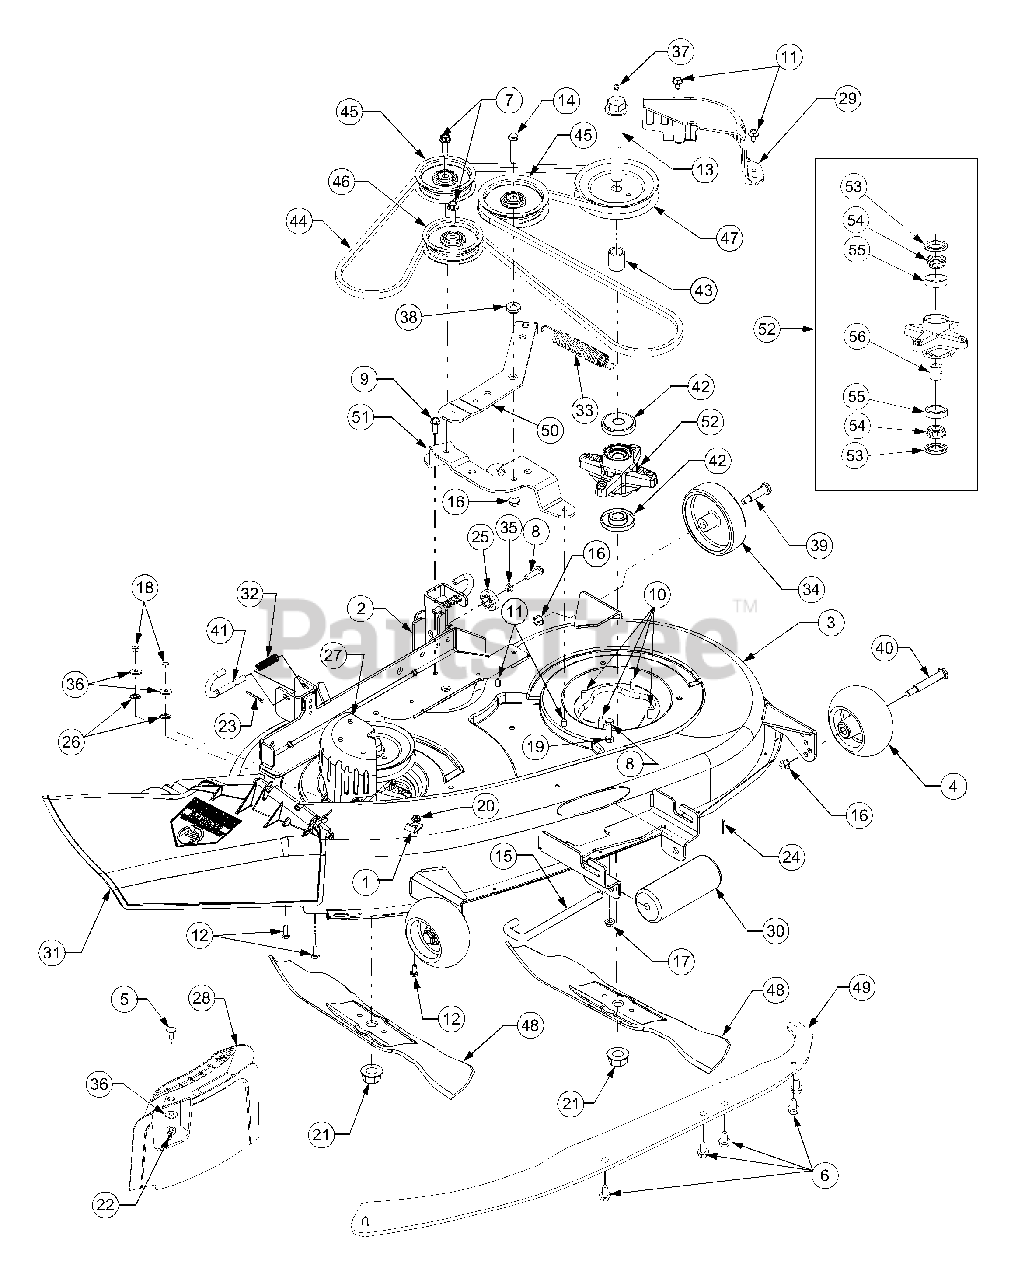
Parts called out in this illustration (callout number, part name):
1	Bracket, Hook, Retainer
5	Screw, Carriage, 1/4-20 x .62
6	Screw, Hx. Wash, Hd,Tapp 1/4-20 x .5
7	Screw, Hx. Wash, Hd, Sems Tapp 3/8-16 x 1.25
8	Screw, 5/16-18, 1.25, Gr5
9	Screw, Hx. Wash, Hd, Tapp, 5/16-18 x 1.0
10	Screw, Hx. Wash, Hd, Tapp, 5/16-18, 0.875
11	Screw, Hx. Wash, Hd, Tapp, 5/61-12 x .75
12	Screw, 1/4-20, .620, Gr5
13	Bolt, Spindle, 3/4-16, 5.85 (solid bolt, no grease fitting)
13	Bolt, Spindle, 3/4-16, 5.85 Greaseable spindle (No longer available) replace with 710-04226, 618-04217 & 737-3000
14	Screw, Hx. Cap, 3/8-16, 2.00, Gr5
15	Roller Pin 1/2" x 7.31 Lg
16	Nut, Hx. Flange Lock, 3/8-16
17	Nut, Hx. Flange Lock, 5/16-18, Gr5
18	Nut, Hex, 1/4-20, Gr5
19	Nut, Hex, 5/16-18, Gr5
20	Nut, Hx. Flange Lock, 1/4-20
21	Nut, Hx. Flange, 3/4-16
22	Nut, Wing, 1/4-20
23	Pin, Cotter, 1/8 x 1.25
24	Pin, Cotter, 3/32 x 1.25
25	Adjustment Gear, Deck
26	Nut, Push, .25 ID x .50 OD
27	Cover, Belt, Deck
28	Plug, Mulch
29	Cover, Belt, Deck, LH
30	Front Roller
31	Chute Assembly, Side Discharge Includes the following parts
32	Spring, Compression, .406 x .531 x
33	Spring, Extension .94 x 7.57
34	Wheel Deck 5.0 x 1.38
35	Washer, Lock, 5/16, Regular Duty
36	Washer, Belleville, .265 x .75 x .062
37	Fitting, 3/16 Drive Lube
38	Spacer, Shoulder, 1.00 x .38 x .38
39	Shoulder Screw
40	Shoulder Screw - 1/2 Dia x 2.50 Lg.
41	Rod, Handle, Deck Release .375 Dia
42	Spacer, Spindle, Deck
43	Spacer, .80 x 1.10 x 1.330
44	Belt, V-Type
45	Pulley, Idler, 3.50 Dia.
46	Pulley, Idler, 4.06 Dia. w/ Flange
47	Pulley, Spindle
48	Blade, 19.38 Lg, 3-in-1
52	Spindle Housing Assembly (Non Greaseable) Includes Ref. Nos. 53 thru 56
53	Seal, Oil, Single Lip
54	Bearing, Cone
55	Cup, Bearing
56	Spacer, Bearing, .780 x 1.000 x
